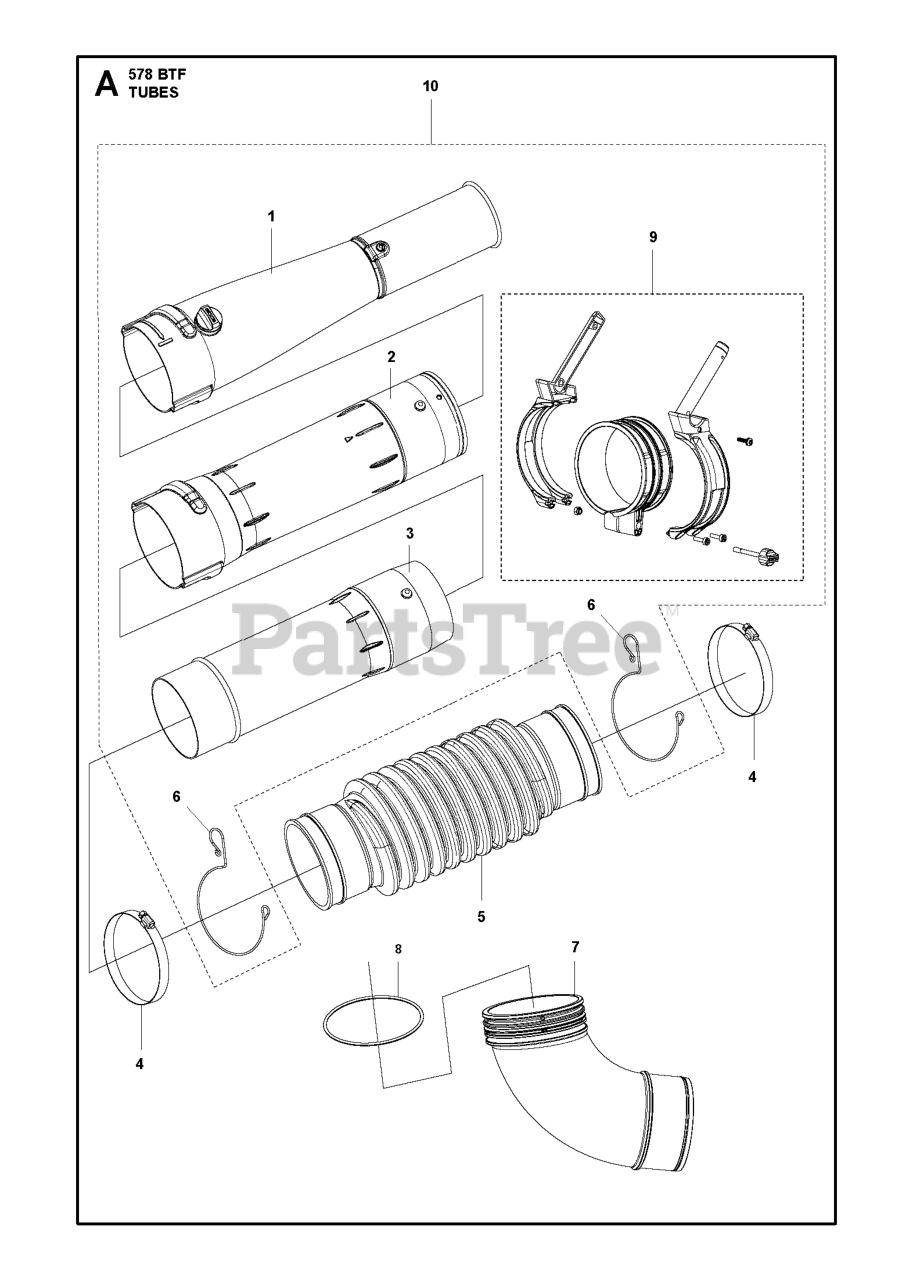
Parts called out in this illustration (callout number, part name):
3	PIPE
4	CLAMP(F115)
5	HOSE
6	CLAMP
7	PIPE ELBOW
